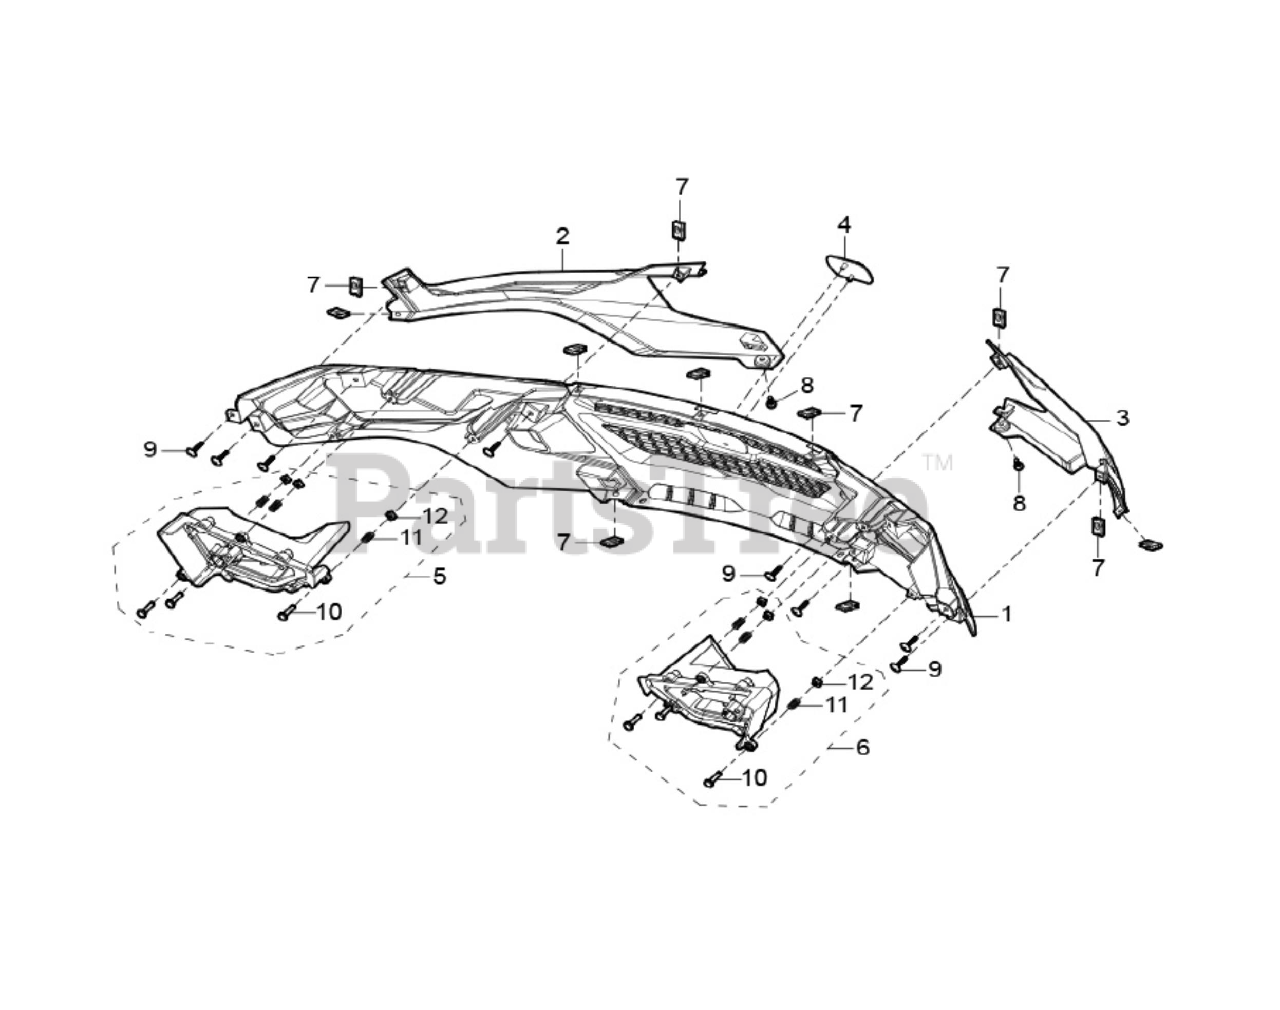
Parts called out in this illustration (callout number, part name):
1	HEAD LIGHT DASH
2	COVER HEAD LAMP(LEFT) RED
2	COVER HEAD LAMP LEFT YELLOW
2	COVER HEAD LAMP LEFT BLUE
2	COVER HEAD LAMP LEFT BLACK
2	COVER HEAD LAMP LEFT CAMO
3	COVER HEAD LAMP RIGHT RED
3	COVER HEAD LAMP RIGHT YELLOW
3	COVER HEAD LAMP RIGHT BLUE
3	COVER HEAD LAMP RIGHT BLACK
3	COVER HEAD LAMP RIGHT CAMO
4	FRONT PANEL EMBLEM
5	HEAD LIGHT ASSEMBLY - LEFT
6	HEAD LIGHT ASSEMBLY - RIGHT
7	CLAMP NUT M6X6
8	SOCKET HEX FLAT HEAD BOLT M6X16
9	CROSS LARGE PLATE HEAD SCREW M6X16
10	HEX HEAD BOLT M6 X 25
11	COMPRESSION SPRING
12	SQUARE NUT M6
